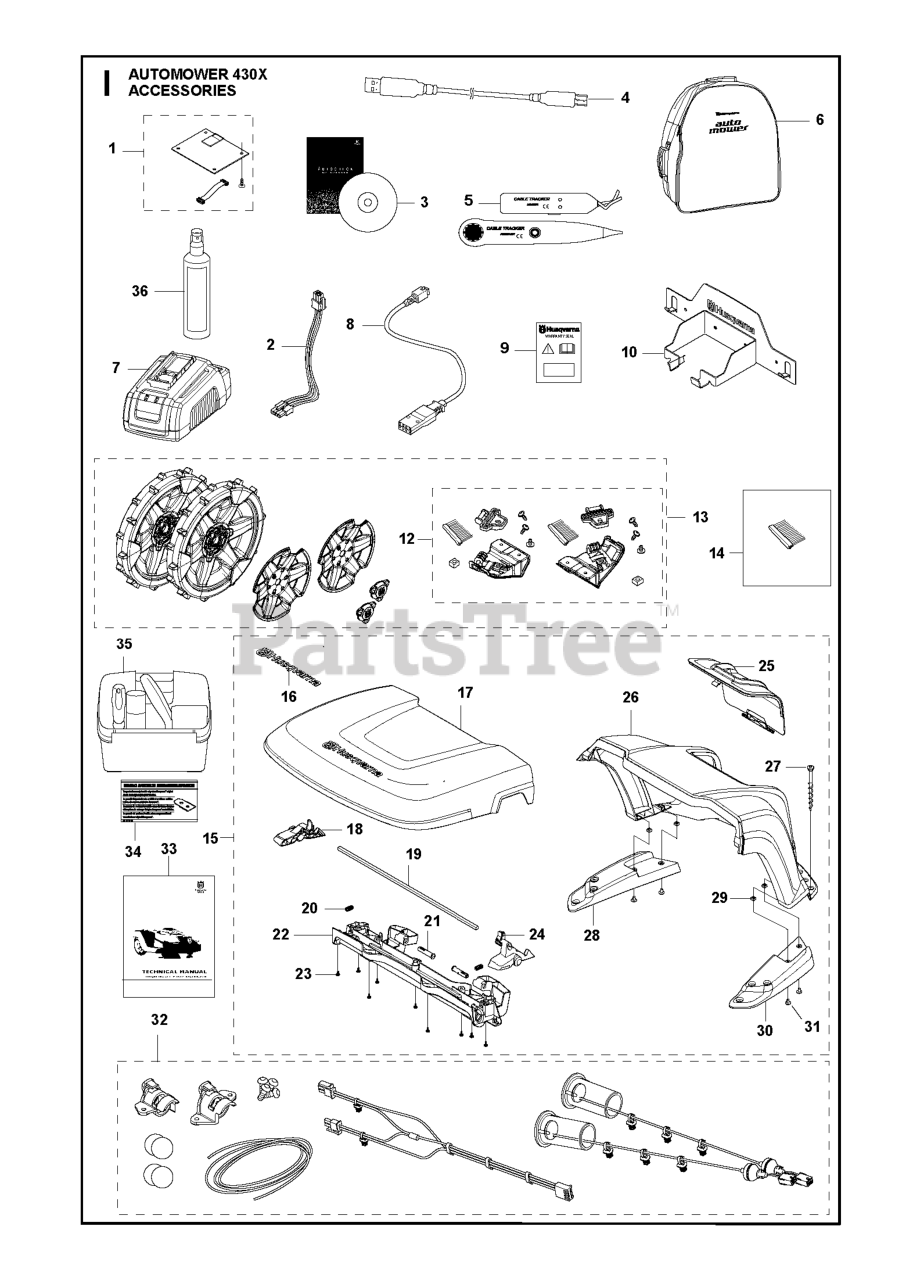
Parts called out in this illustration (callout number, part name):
1	CONNECT MODULE 2G / 3G
2	WIRING ASSY BATTERY CABLE
3	DVD AUTOCHECK EXP SERVICE
4	CABLE WHITE ALT GREY
5	TEST EQUIPMENT
6	BAG
7	CHARGER BATTERY TEST
8	CABLE ASSY QUICK CHARGER
9	LABEL WARRANTY SEAL DEALER
10	MISC. BLISTER WALL HANGER
12	BRUSH KIT 430/450
13	REAR WHEEL KIT W/ BRUSHES
14	WHEEL BRUSH REFILL KIT
15	430/450 HOUSE KIT
16	DECAL.HUSQVARNA.210MM
17	KIT LID - AUTOMOWER HOUSE
18	HANDLE RELEASE LEFT
19	ROD
20	SPRING SPRING CAP
21	HINGE PIN
22	BEAM
23	SCREW 14MM
24	HANDLE RELEASE RIGHT
25	HATCH
26	COVER BASE P2 HOUSE
27	SCREW KIT CS
28	SUPPORT BASE LEFT
29	NUT
30	SUPPORT BASE RIGHT
31	SCREW IHPANM M6X25 4.6 ZP-BC
32	430 HEADLIGHT KIT
34	ORIGINAL PARTS STICKER
34	DECAL WARNING ORIGINAL BLADE E
35	CLEANING AND MAITENANCE KIT AM
